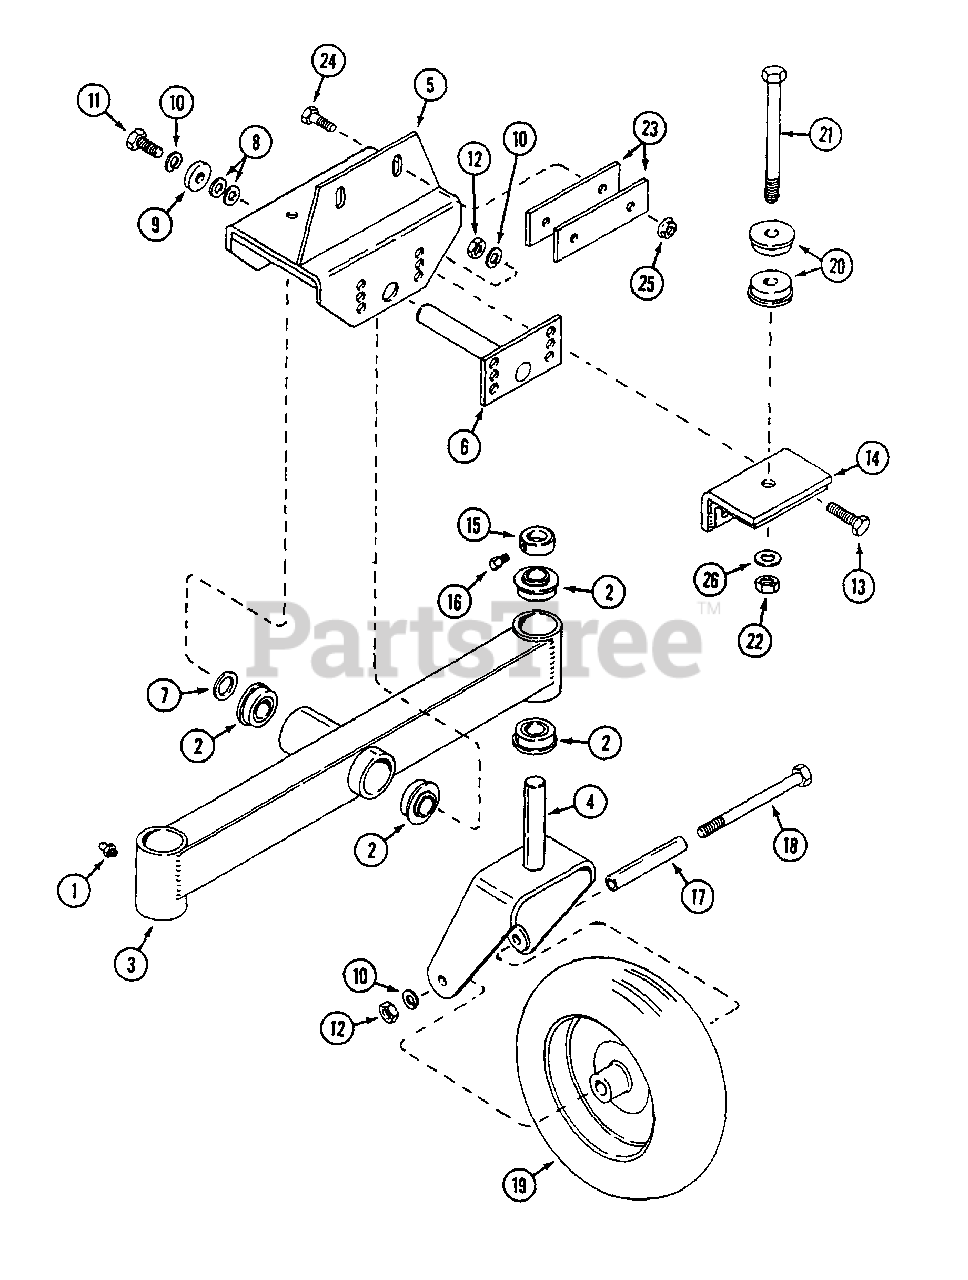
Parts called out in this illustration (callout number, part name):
1	FITTING - lubrication 1/4" - 28
2	BEARING - ball 1"
3	AXLE - dual wheel
6	ROD - axle pivot
7	WASHER - 1" x 1-3/4"
8	WASHER - 1/2" x 1"
9	WASHER - 1/2" x 1-3/8"
10	LOCKWASHER - 1/2"
12	NUT - 1/2" - 13
13	BOLT - 1/2" - 13 x 1-3/4"
14	MOUNT - axle, front extension
15	COLLAR - set 1"
16	SCREW - set 5/16" - 18 x 1/2" square head
18	BOLT - 1/2" - 13 x 7"
19	WHEEL ASSEMBLY
20	BUSHING - tail wheel hub
21	BOLT - 5/8" - 11 x 7-1/2"
21	BOLT - 5/8" - 11 x 11"
22	NUT - 5/8" - 11
23	PLATE - stiffener
24	BOLT - 3/8" - 16 x 1-1/4"
25	NUT - 3/8" - 16 flange lock
26	WASHER - 5/8" x 1-1/2"
